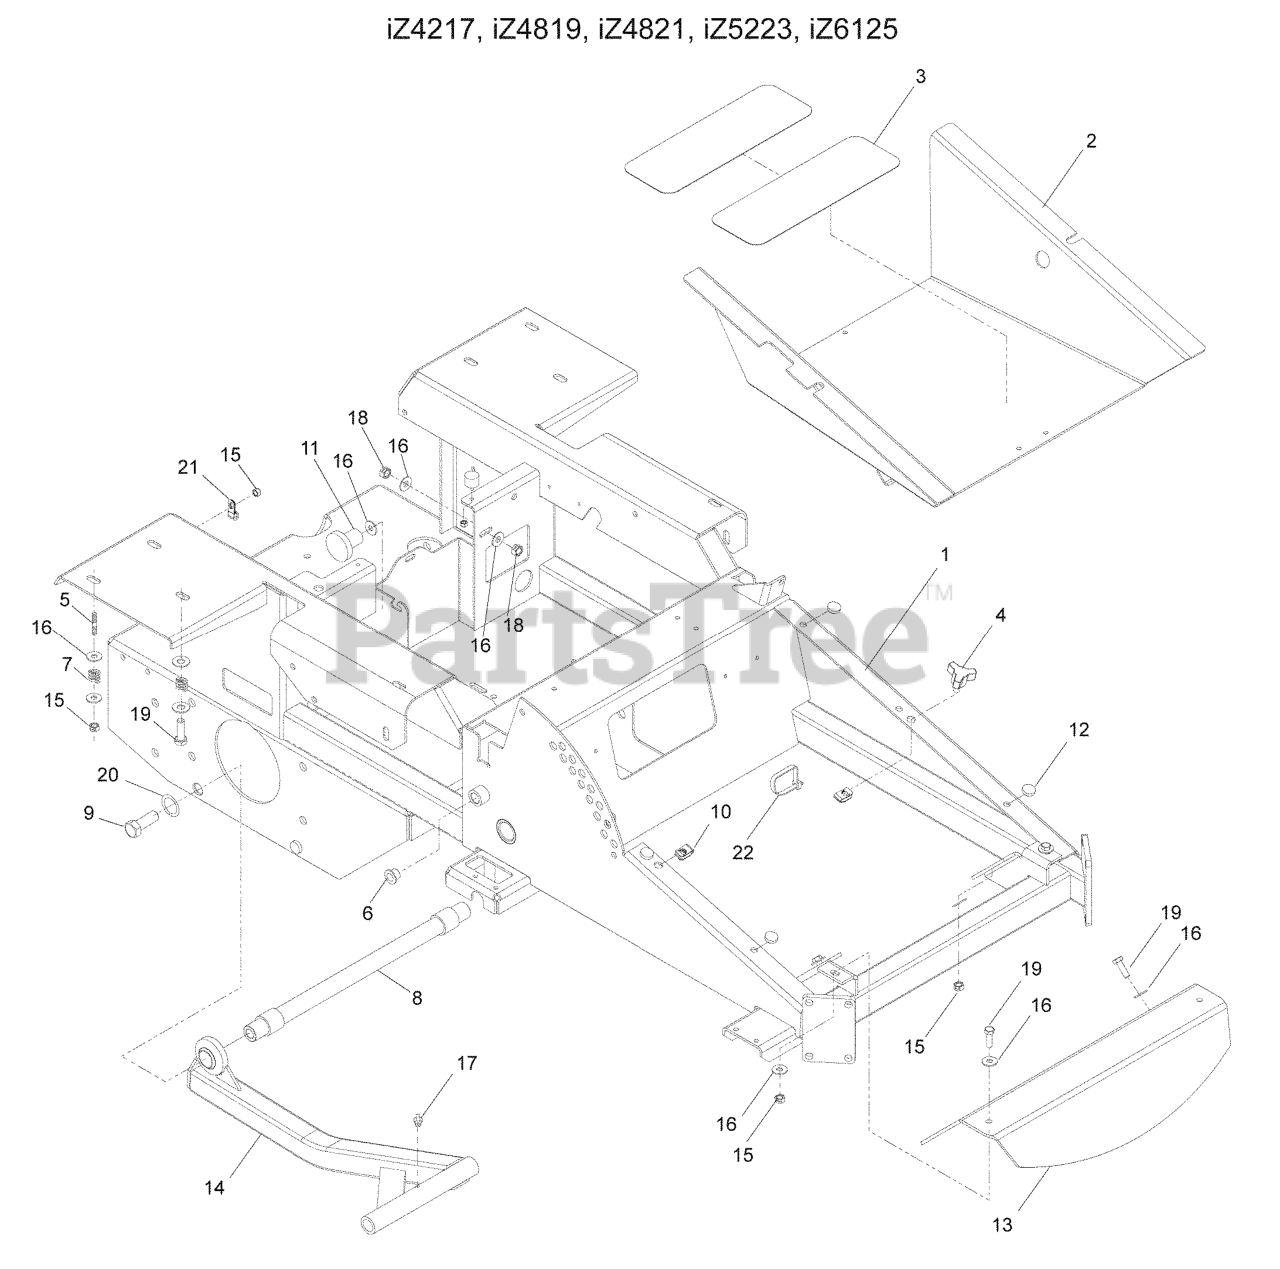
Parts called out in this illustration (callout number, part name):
1	IZ FRAME W/DECALS
2	IZ FOOTPLATE W/DECAL
3	ANTI-SKID PAD
4	KNOB W/STUD
5	STUD, 5/16C
8	STRUT MOUNT WELDMENT
9	HCS 5/8C X 2 GR.5
10	U-CLIP 5/16-18 NUT RETAINER
12	GROMMET, BUMPER
13	FOOTREST ORANGE
15	NUT 5/16 NYLOC
16	WASHER 5/16 FLAT
17	ZERK
18	NUT 5/16C CENTERLOCK
19	HCS 5/16C X 1
20	LOCKWASHER 5/8
21	DOUBLE TUBE CLAMP
22	TIE, PLASTIC
